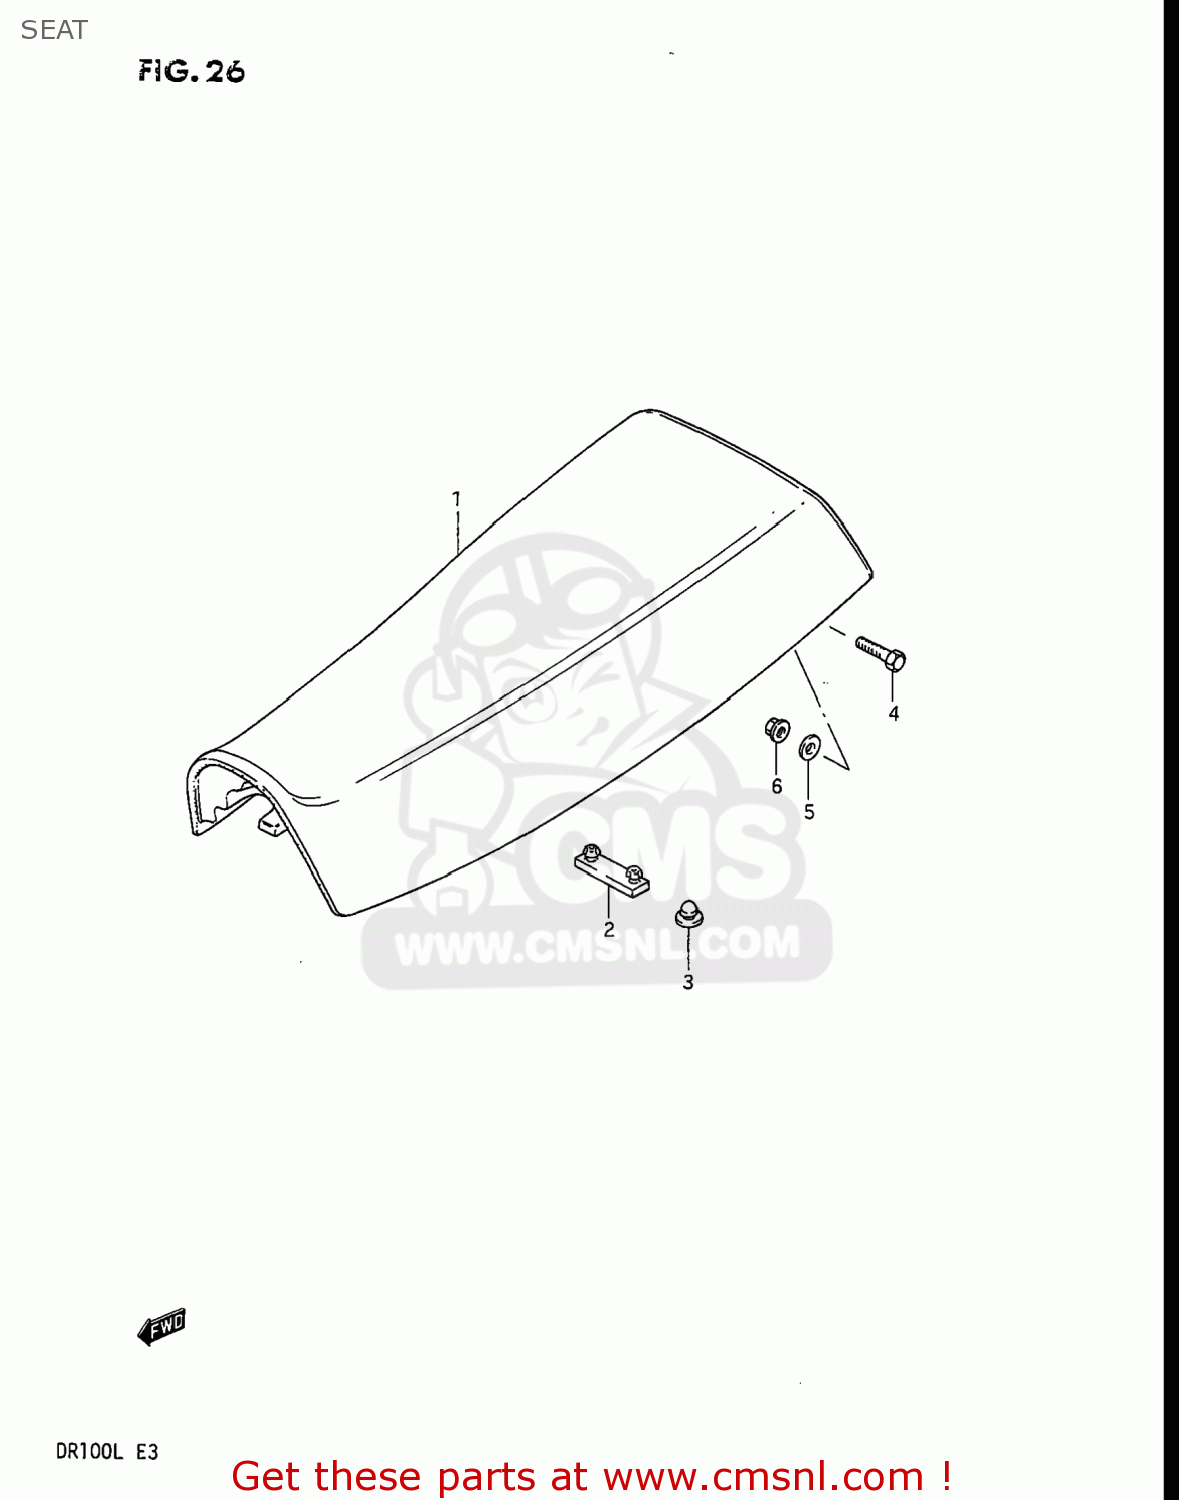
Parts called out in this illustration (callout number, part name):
1	SEAT ASSEMBLY
2	CUSHION
3	CUSHION
4	BOLT, LOWER
5	WASHER(8.5X23X1.2)
6	NUT
